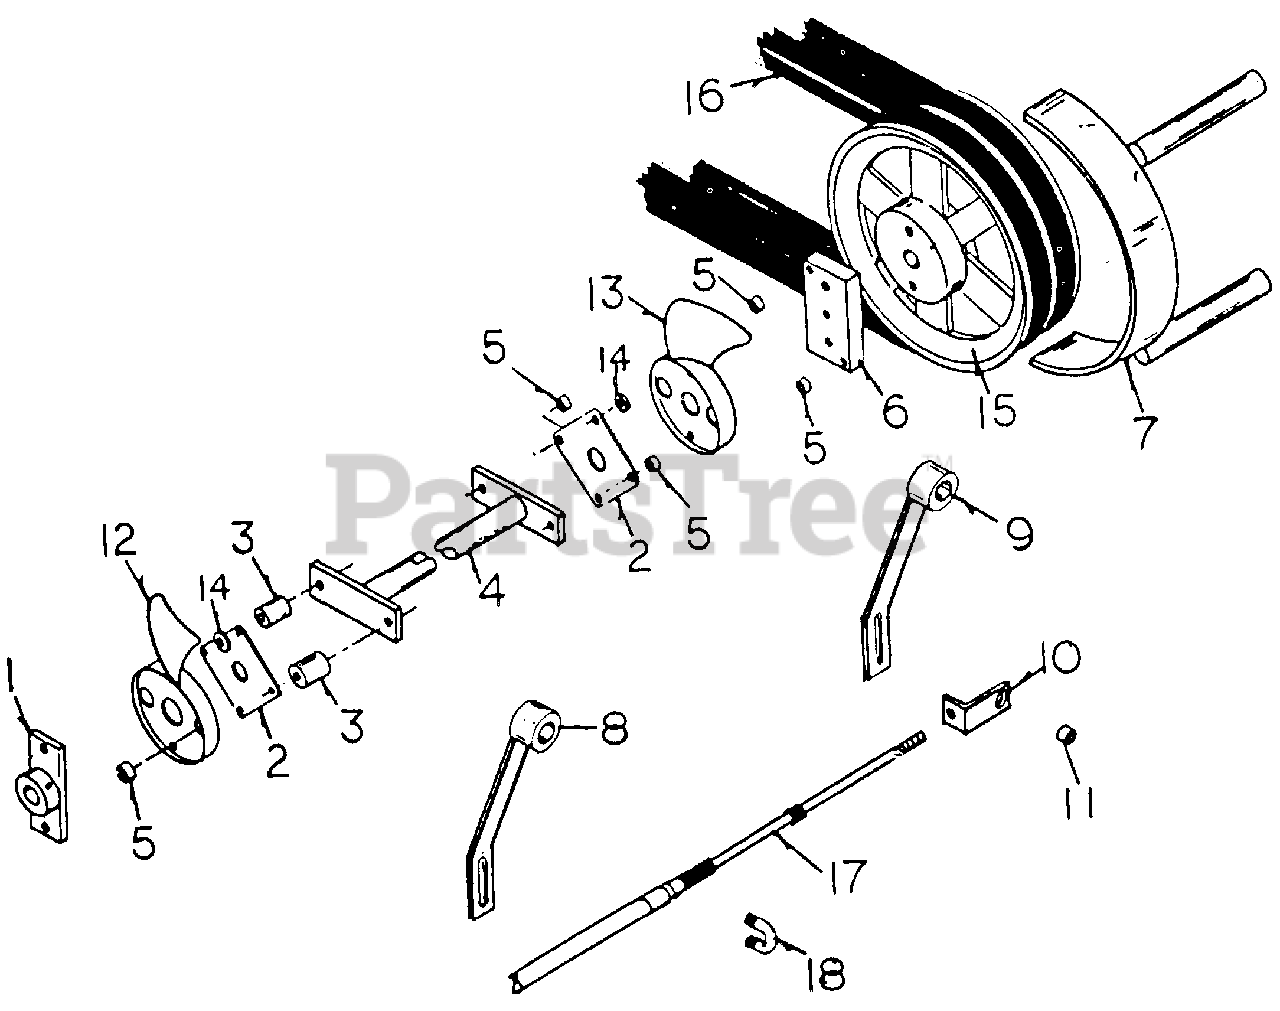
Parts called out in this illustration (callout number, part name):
1	Hub w/Drive Plate
2	Drive Plate
3	Spacer
6	Cross Bar Block
7	Transmission Belt Retainer
8	Transmission Arm, LH
9	Transmission Arm, RH
10	Steering Cable Ends
11	Steering Cable Ends Bushing
17	Steering Cable
